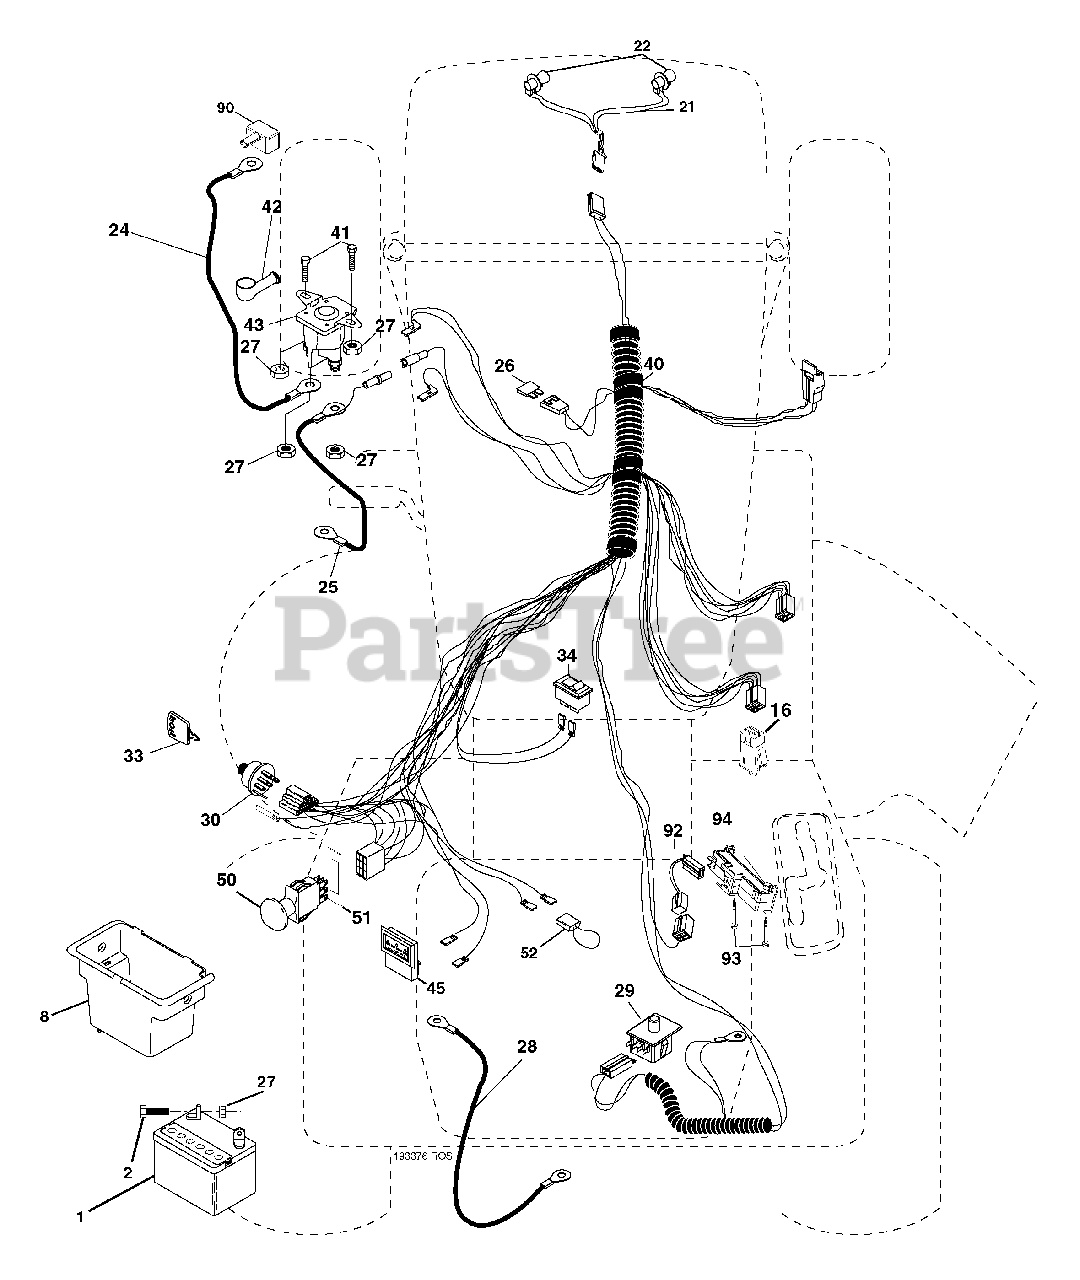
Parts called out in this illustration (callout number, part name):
1	Battery
2	Bolt Hex Hd 1/4-20 unc x 3/4
8	Box Battery
16	Switch Interlock
21	Harness Socket Light
22	Bulb, Light # 1156
24	Cable Battery
25	Cable Battery 6 Ga. Red w/16 wire 44"
27	Nut Keps Hex 1/4-20 unc
28	Cable Ground 12" Blk 6 Ga.
29	Switch Seat
30	Switch Ign
33	Key Ign Molded Generic
34	Switch Light/Reset
40	Harness Ign
41	Bolt Fin Hex 1/4-20 unc x 1/2
42	Cover Terminal Red
43	Solenoid
50	Switch PTO
51	Ring Retainer PTO
52	Hourmeter Adapter
90	Cover Terminal
92	Harness Pigtail Reverse Switch
93	Screw Plastite 10-14 x 2.0
94	Module Revers ROS
